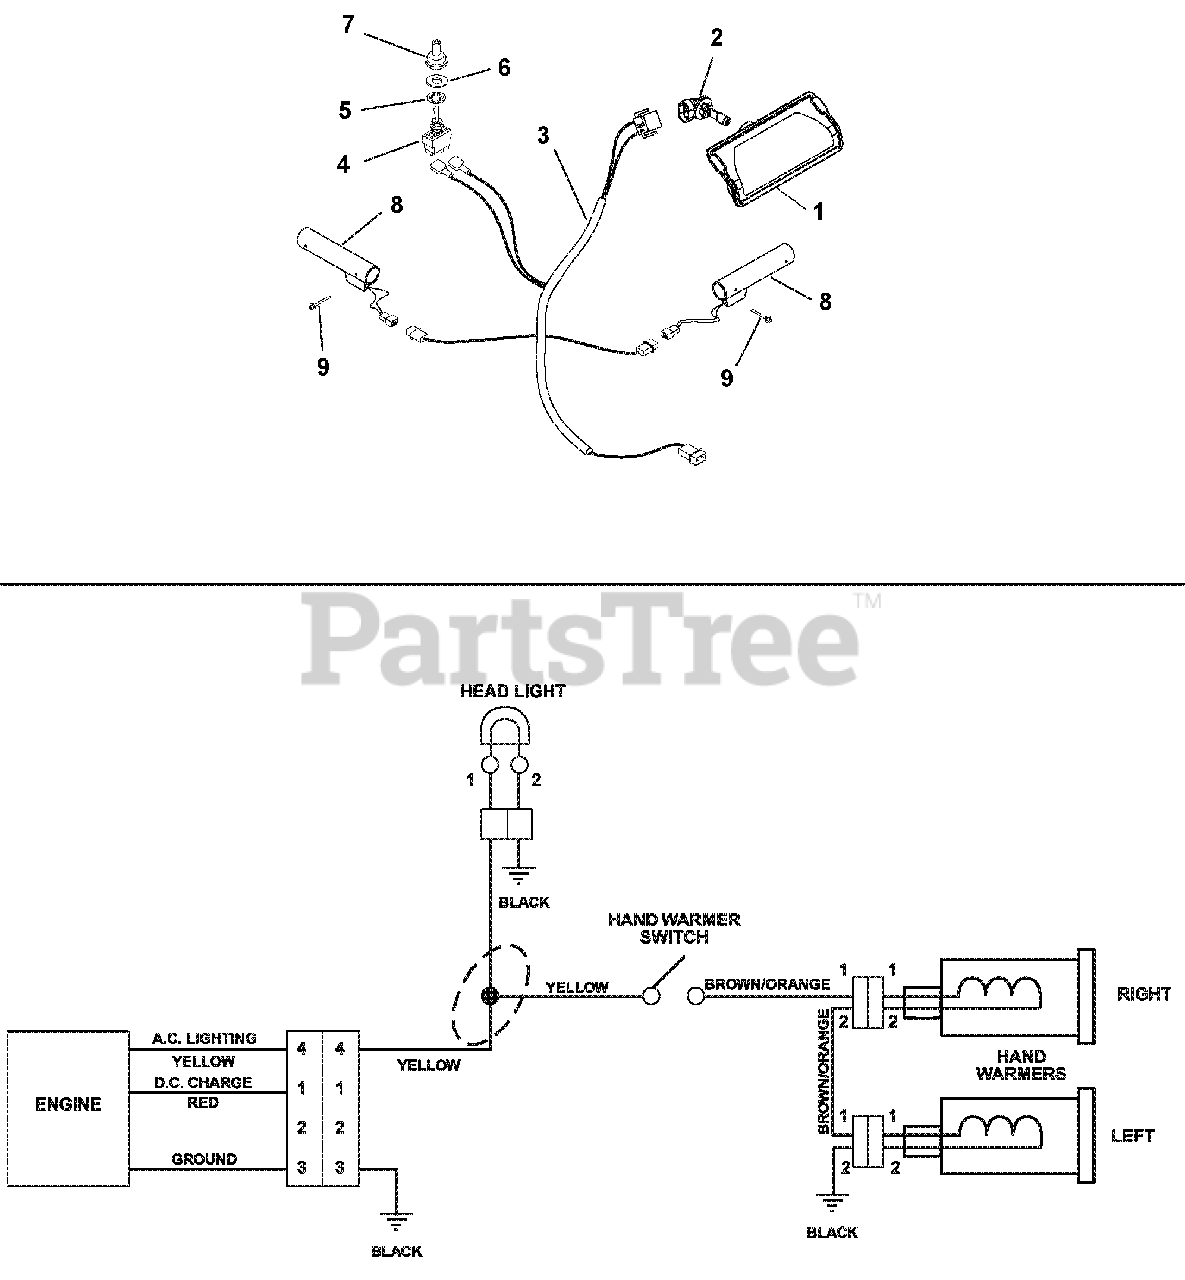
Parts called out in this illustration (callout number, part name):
1	HEADLIGHT ASY, HALO 20W 2SHOT
2	BULB, LIGHT-HALOGEN 20W
3	HARNESS, LIGHT & WARMER
4	SWITCH, ON/OFF
5	WSHR-LK-INT .563X.040 YWZC
6	WSHR-FL-STL .505X.875X.024 PL
7	BOOT, SWITCH
8	HEATED GRIP, MAGURA
9	RVT-POP #43 .125X.313 STL ZINC
